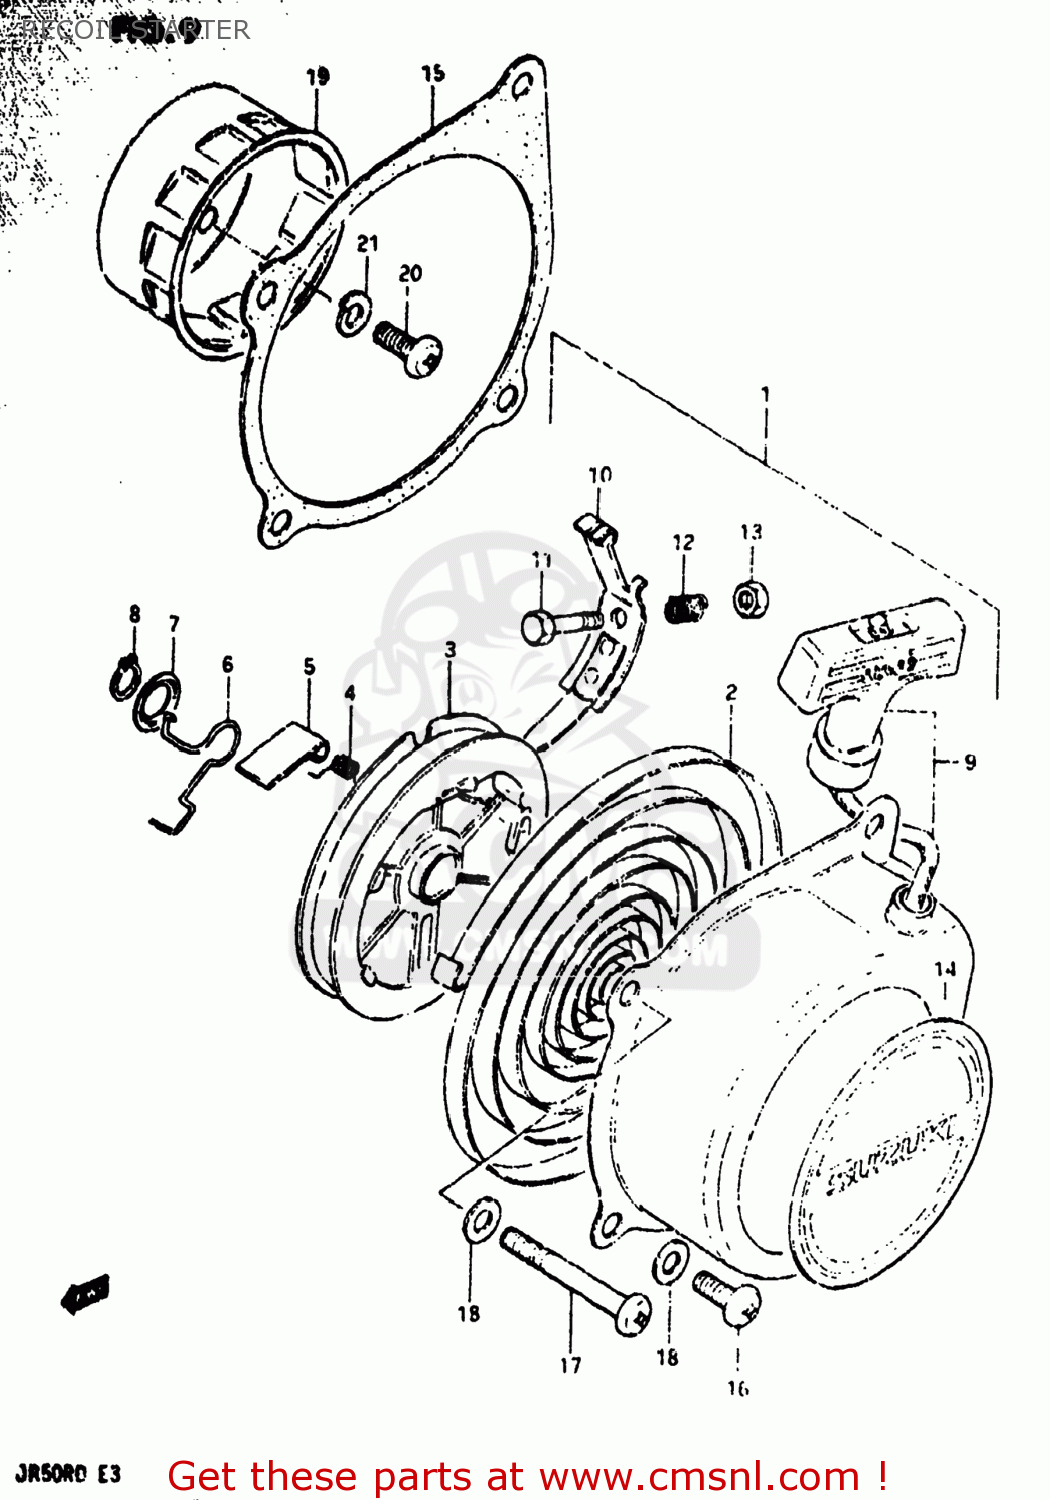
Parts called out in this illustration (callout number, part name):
1	STARTER ASSEMBLY,RECOIL
2	SPRING,SPIRAL
3	REEL
4	SPRING,DOG
5	DOG
6	LEVER
7	WASHER
8	CIRCLIP
9	GRIP ASSEMBLY
10	SPRING,LEVER ASSEMBLY
11	BOLT
12	SPRING
13	NUT
14	EMBLEM
15	GASKET,STARTER (NAS)
16	SCREW 6X12
17	SCREW
18	WASHER
19	CUP,STARTER
20	SCREW 6X12
21	LOCK WASHER
